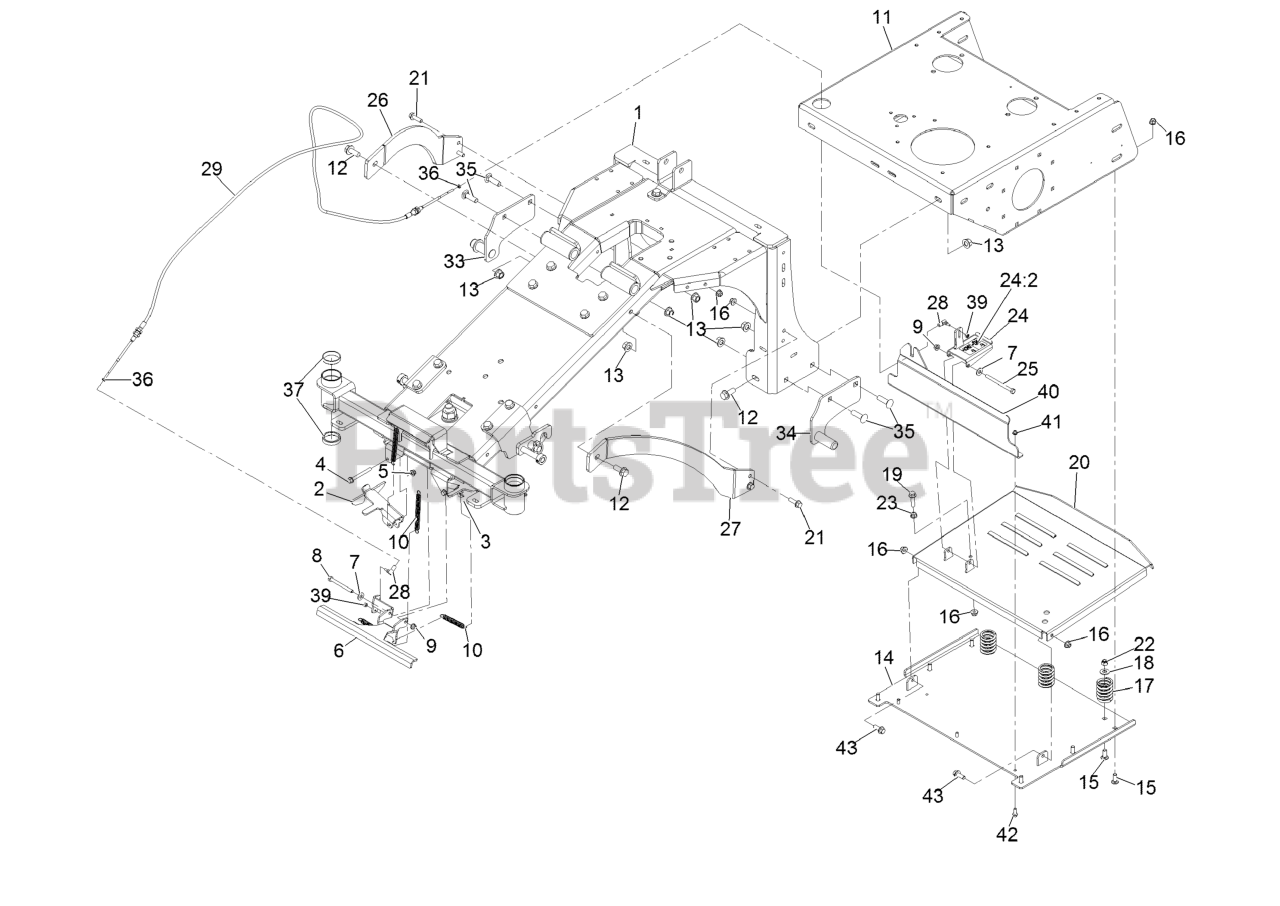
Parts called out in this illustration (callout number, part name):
1	Front Frame ASM
2	WING-CASTER RH
3	WING-CASTER LH
4	SCREW-HHF
5	Nut-Hex Flange
6	ARM-BODY, LCS
7	Washer-Flat
8	SCREW-HH
9	NUT-HF, NI
10	SPRING-EXTENSION
11	REAR FRAME ASM
12	SCREW-HHF
13	Nut-Lock 1/2-13
14	FRAME BASE
15	SCREW-CARR
16	NUT-HF, NI
17	SPRING-COMPRESSION
18	Washer-Flat
19	SCREW-HHF
20	WLD, FOOTPLATE, AE
21	SCREW-HHF
22	NUT-LOCK, NI
23	NUT-HEX FLANGE
24	PEDAL-FOOT
24:2	Decal-Lock, Caster
25	SCREW-HH
26	BRACE-FRAME, RH
27	BRACE-FRAME, LH
28	BALL JOINT-SS
29	ZPLUG LOCKING CASTER CABL
33	PIVOT-BRAKE, RH
34	PIVOT-BRAKE, LH
35	SCREW-CARR
36	Nut,Hex Jam Mch Scr,10-32,Sst
37	BEARING-CUP, TAPERED
39	Nut,NYL Lock,#10-32,ST/ST 18-8
40	SHIELD-HEAT, MUFFLER
42	SCREW-HHF
43	SCREW-HHF 3/8-16 X 1
